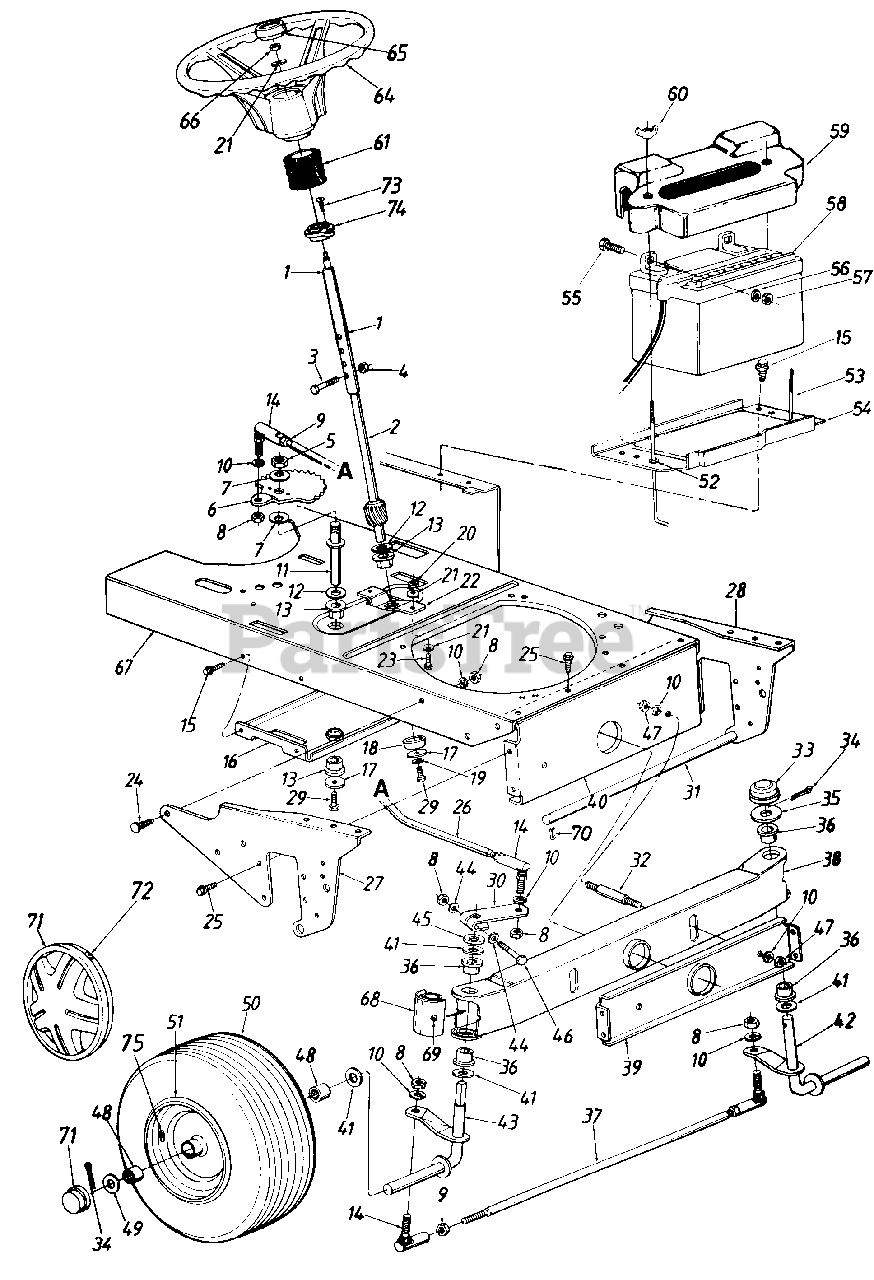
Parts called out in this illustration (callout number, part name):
1	Steering Column Ass'y.
2	Lower Steering Shaft
3	Hex Bolt 1/4-20 x 1.31" Lg.
4	Hex L-Nut 1/4-20 Thd.
5	Hex Nut 5/8-18 Thd.
6	N Steering Gear Segment
7	Bell-Wash. 5/8" I.D. x 1.25" O.D.
8	Hex Nut 3/8-24 Thd.
9	Hex Jam Nut 3/8-24 Thd.
10	L-Wash. 3/8" I.D.
11	Steering Gear Segment Shaft
12	Fl-Wash. .64" I.D. x 1.24" O.D.
13	Hex Flange Brg. .63" I.D.
14	Ball Joint Ass'y.
15	Hex Wash. Hd. TT-Tap Scr. 1/4-20 x .5" Lg.
16	Deck Idler Support Brkt.
17	Fl-Wash. .33" I.D. x 1.25" O.D.
18	Spacer .985" I.D. x 1.25" O.D.
19	L-Wash. 5/16" I.D.
20	Hex Nut 5/16-24 Thd.
21	Bell-Wash. .345" I.D. x .88" O.D.
24	Ribbed Neck Bolt 3/8-24 x .8" Lg.
25	Hex Wash. TT-Tap Scr. 5/16-18 x .62" Lg.
26	Steering Drag Link
27	Pivot Bar Side Plate R.H.
28	Pivot Bar Side Plate L.H.
29	Hex Bolt 5/16-18 x .62" Lg.
30	Steering Arm
31	Deck Connecting Rod
32	Pivot Bar Shld. Bolt 3/8-16 x 5/8" Lg.
33	Cap
34	Cotter Pin 5/32" Dia.
35	Flat Washer
36	Flange Brg. .757" I.D.
37	Tie Rod 20.25" Lg.
38	Pivot Bar Assy.
41	Fl-Wash. .76" I.D. x 1.49" O.D.
42	Front Axle Ass'y. L.H.
43	Front Axle Ass'y. R . H .
44	Bowed Washer
45	Spacer .755" I.D. x 1.25" O.D.
46	Hex Bolt 3/8-24 x 2.25" Lg.
47	Hex Nut 3/8-16 Thd.
48	Flange Brg. .751' I.D.
49	Fl-Wash. .71" I.D. x 1.51' O.D.
51	Rim Only
52	Push Nut
53	Battery Hold Down Rod
54	N Battery Plate
56	L-Wash. 1/4" I.D.
57	Hex Nut 1/4 -20 Thd .
58	N Battery
59	N Battery Cover
60	Wing Nut Plastic 1/4-20 Thd.
61	Steering Bellow
64	Steering Wheel
65	Steering Wheel Cap
66	Hex L-Nut 5/16-24 Thd.
67	Lower Frame
68	Pivot Bar End Cap
69	Grease Fitting
70	Internal Cotter Pin
71	Hub Cap
72	Spring Clip
73	Oval Hd. Cr.-Sunk Scr. #10 x 5/8n Lg.
74	Flange Brg. .89" I.D. x 1.36" O.D.
75	Air Valve
